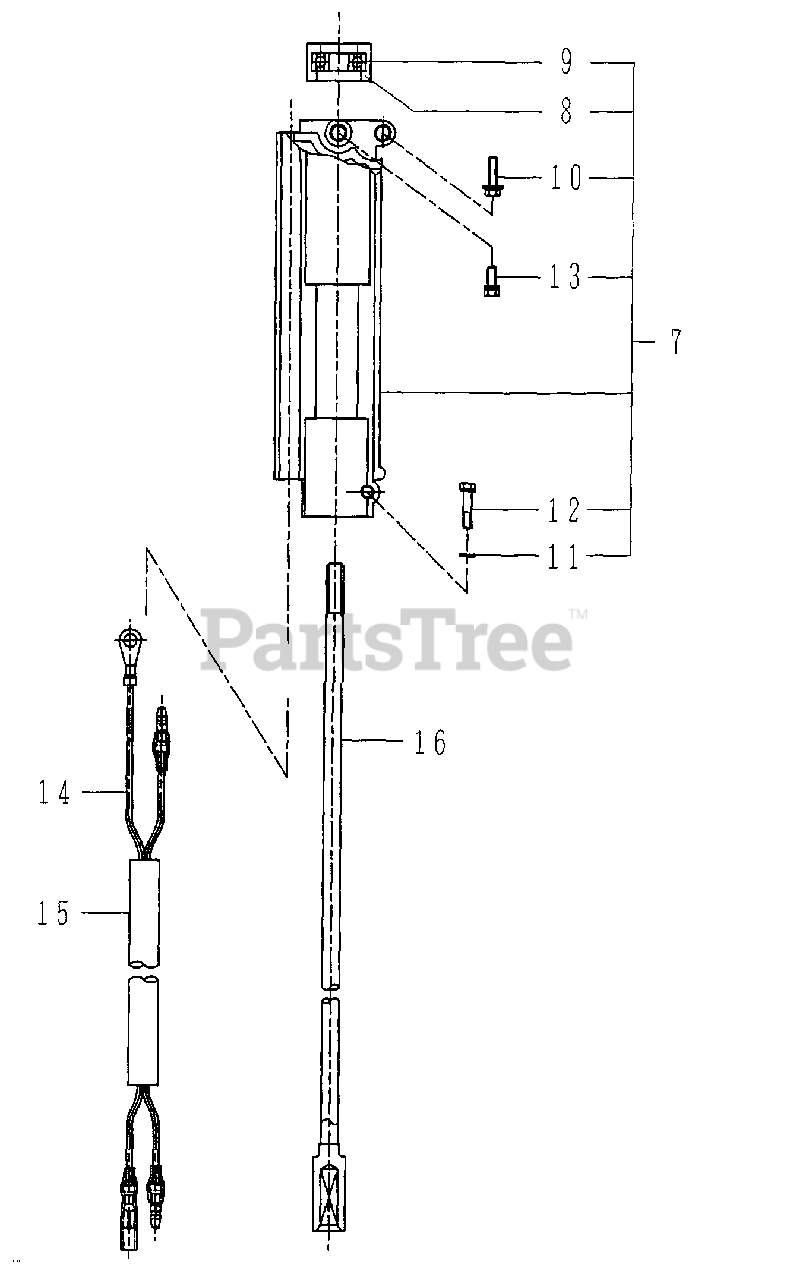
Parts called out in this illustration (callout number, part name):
7	CONNECTOR ASSY, PIPE
8	COVER, BEARING
9	BEARING, BALL
10	BOLT
11	WASHER, SPRING
12	BOLT
13	BOLT
14	LEAD - GROUND
15	PIPE
16	MAINSHAFT
